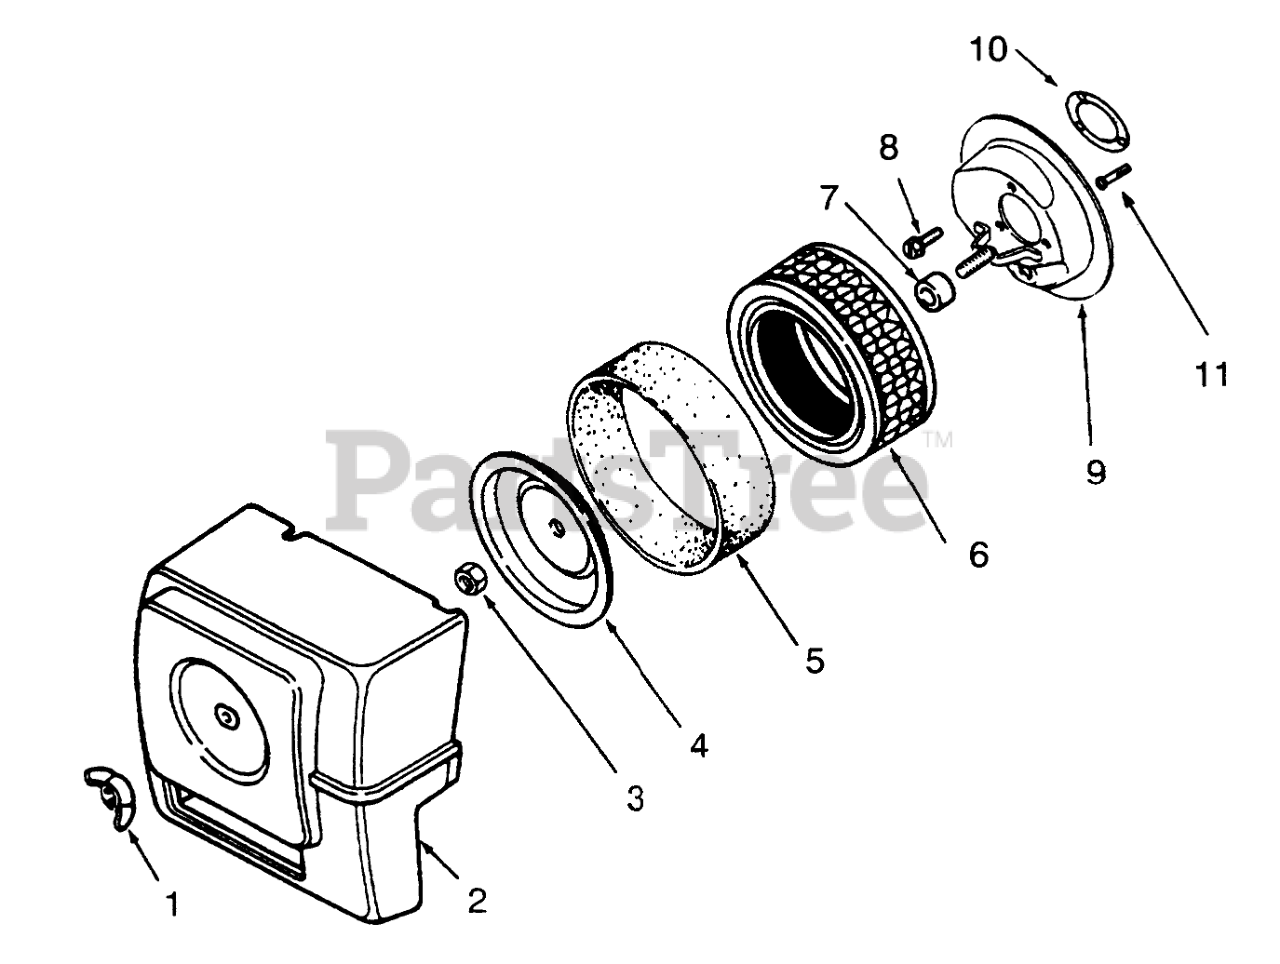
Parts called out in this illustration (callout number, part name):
1	Nut-Wing
2	Cover
4	Air Cleaner Element Cover
5	Element-Precleaner
6	Element
8	Screw
9	Base-AirCleaner
10	Gasket
11	Screw
